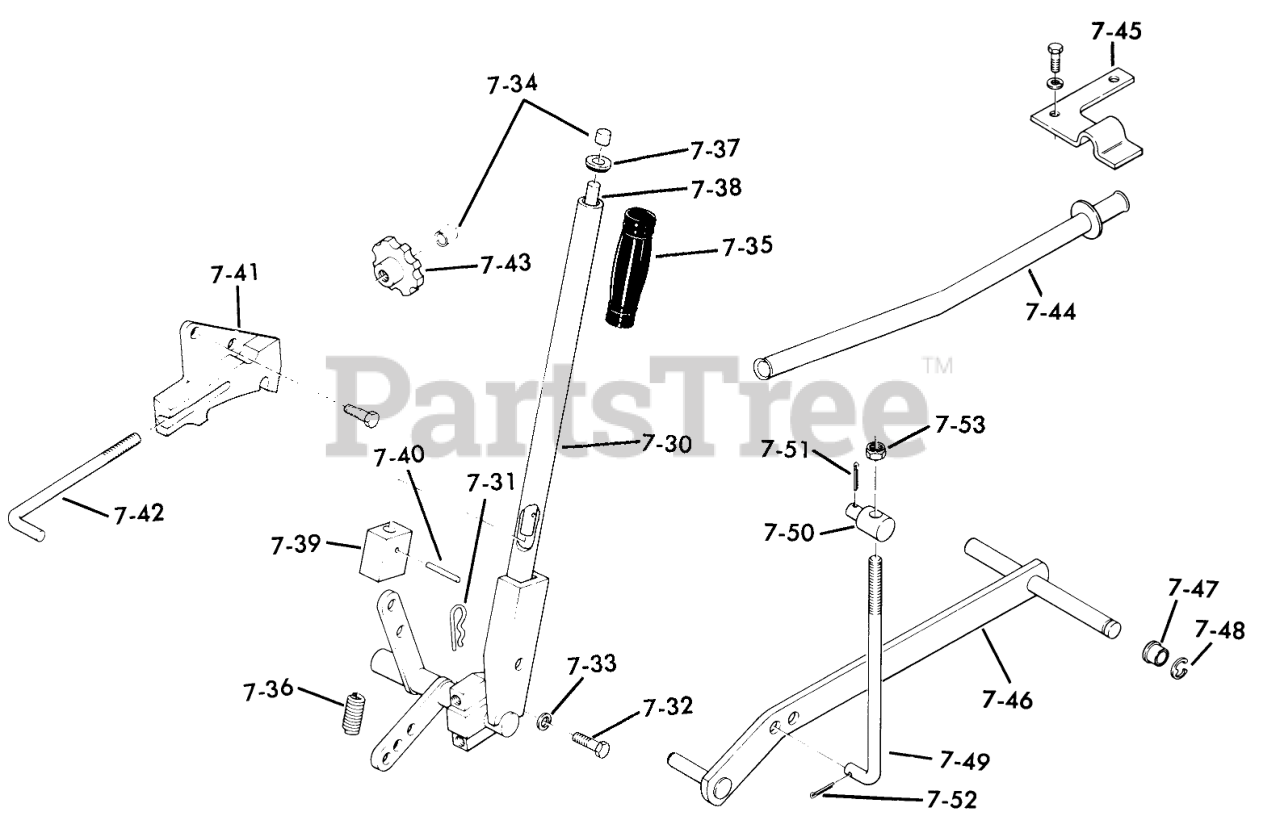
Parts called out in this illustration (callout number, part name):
7-30	Lift Lever
7-31	Hairpin
7-32	H H C S
7-33	Lockwasher
7-34	CAP-ROD, PLUNGER
7-35	HANDGRIP
7-36	SPRING-COMPRESSION
7-37	Guide-Rod
7-38	PLUNGER ROD
7-39	LOWER PLUNGER R
7-40	Roll Pin
7-41	Quadrant
7-42	ROD-LIFT CONTROL
7-43	KNOB-LIFT CONTROL
7-44	TUBE ASSY COMPLET R
7-45	Clamp-Tube
7-46	ASSY LIFT BAR R
7-47	BUSHING
7-48	E Ring
7-49	ROD-LIFT
7-50	TRUNNION-LIFT
7-51	Hairpin
7-52	Cotter Pin
7-53	NUT
